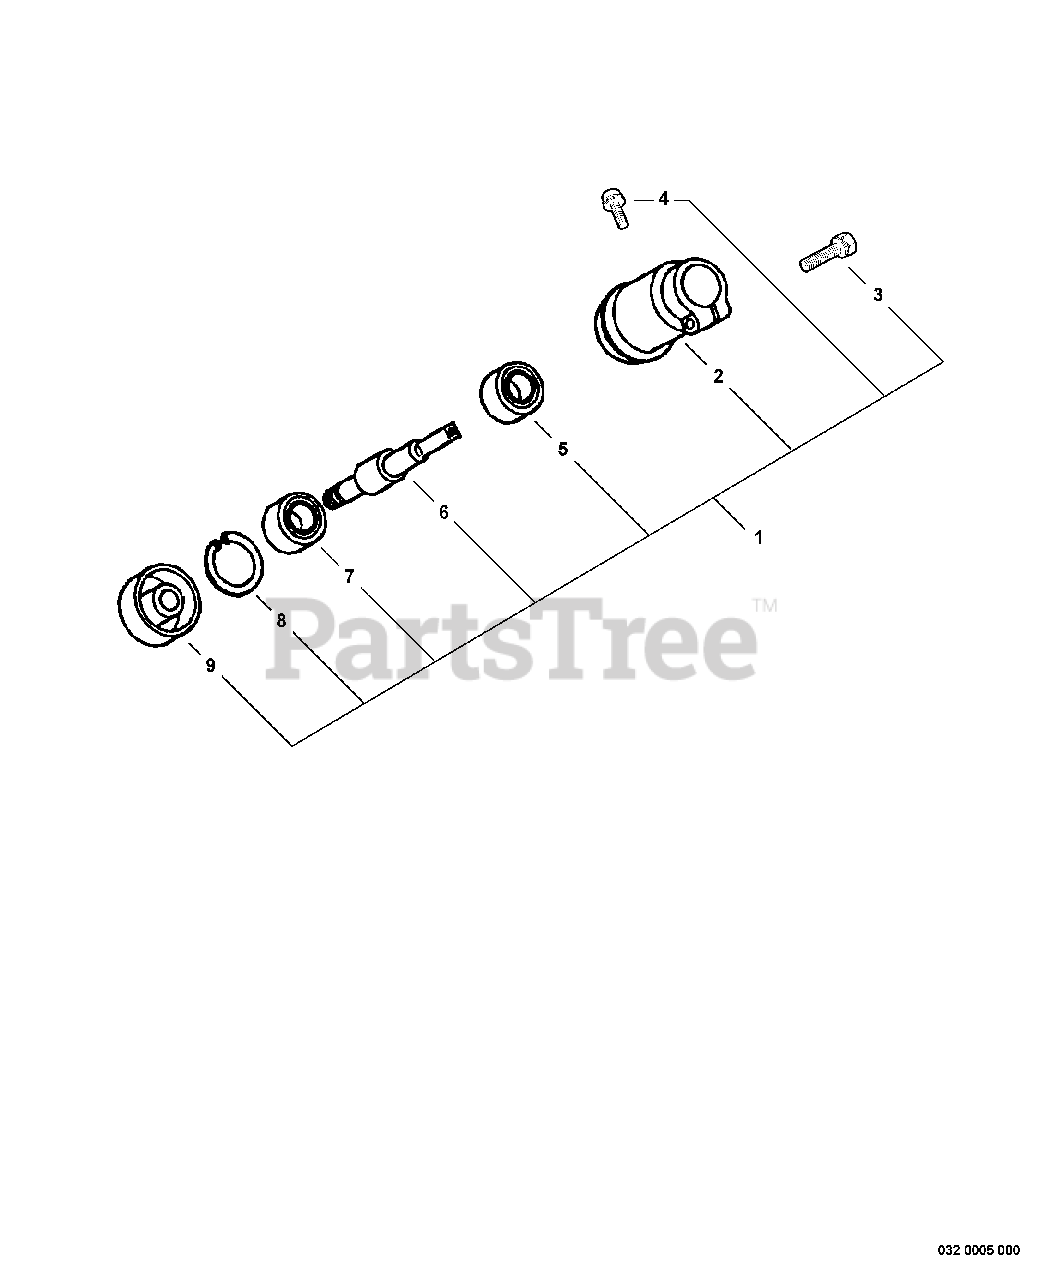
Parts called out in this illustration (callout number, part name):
1	GEAR CASE ASSY
2	CASE, GEAR
3	BOLT - 5×25
4	SCREW 4×10
5	BEARING, BALL 6200
6	GEAR, SHAFT
7	BEARING, BALL 6200
8	E-RING 30
9	PLATE, ADAPTER - UPPER
